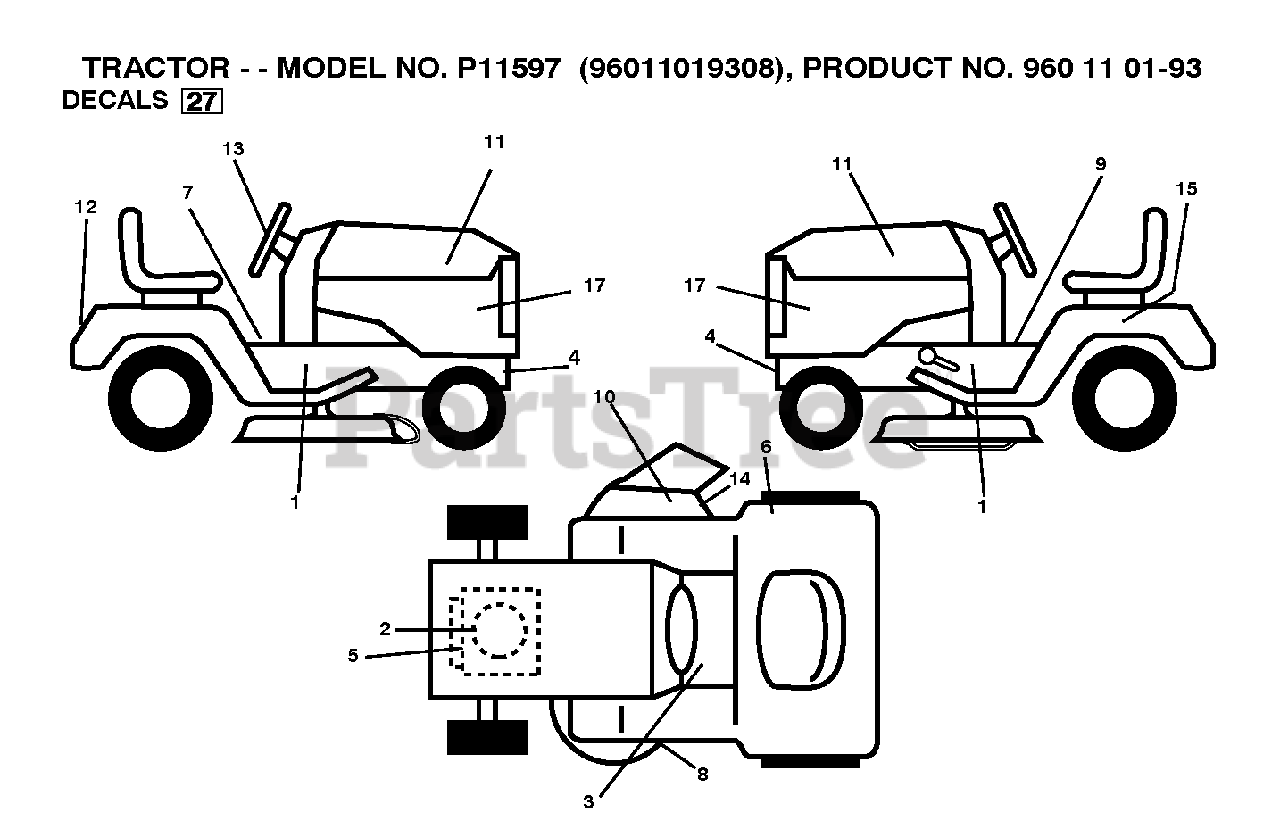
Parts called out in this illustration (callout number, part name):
1	DECAL.CHAS.TURBO
6	Decal, 100 DB/CE
8	DECAL.V-BELT.SCHEMATIC.36/38/9
9	DECAL PARK BRAKE
10	DECAL.INTERNATIONL.CUTFINGER
14	DECAL, DEFLECT WARNING
15	DECAL BTRY SYMBOLS
